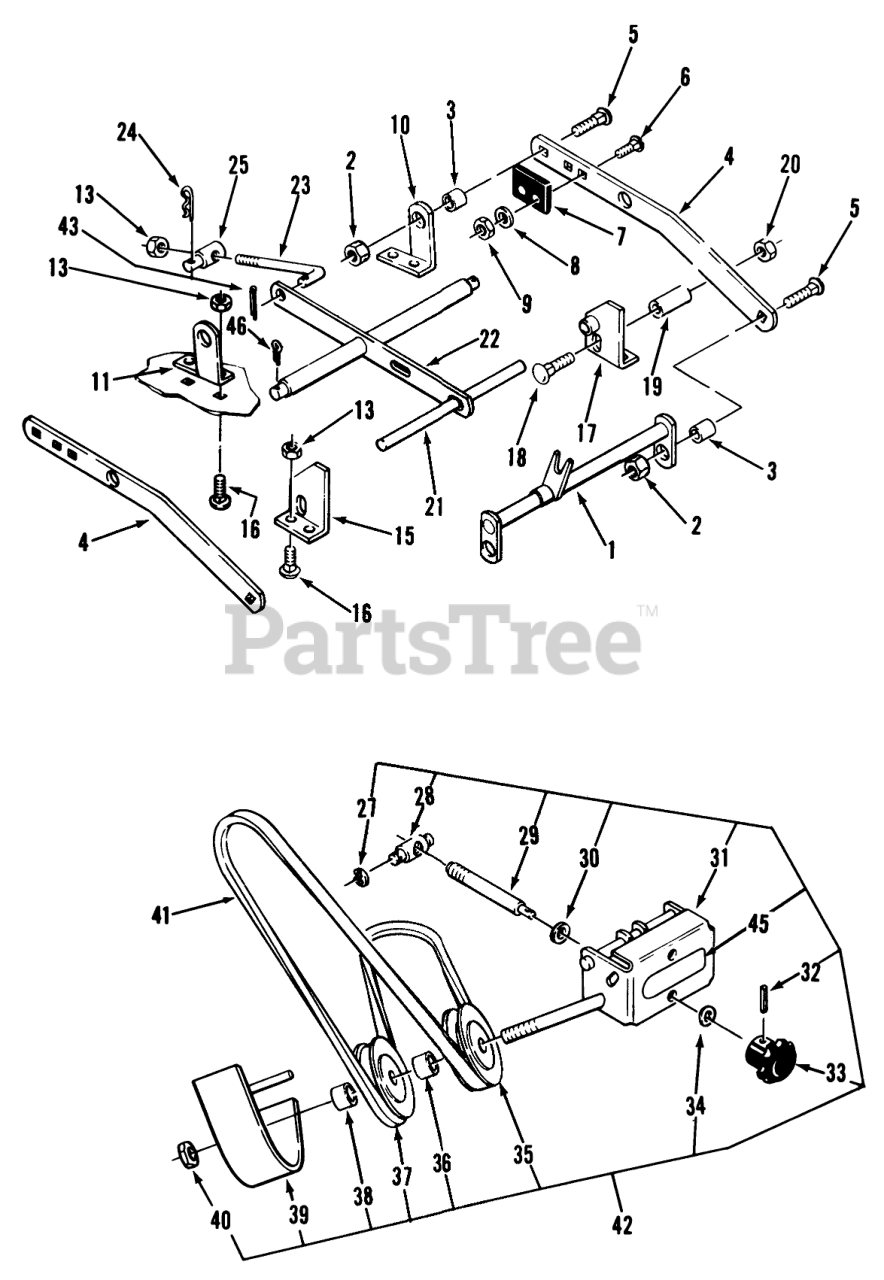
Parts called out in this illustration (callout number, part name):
1	Hitch
2	LOCKNUT-FLANGE
3	SPACER
4	Bar Draft
5	BOLT-CARR
6	SCREW-CARR
7	BUMPER
8	WASHER-FLAT
9	NUT-LOCK, NI
10	LH Rear Bracket
11	Rear Bracket RH
13	NUT-LOCK, NI
15	Front Bracket RH
16	BOLT-CARR
17	Front Bracket LH
18	BOLT-CARR
20	Nut
21	Front Shaft
22	Leveler
23	ROD-LEVEL ADJUST
24	Hairpin
25	TRUNNION-LIFT
27	RING-RETAINING
28	TRUNNION-DOUBLE
29	ROD ADJ
30	WASHER-FLAT
31	Front Support
32	PIN-ROLL
33	KNOB-ADJUSTMENT
34	WASHER-SPRING
35	Pulley-V
36	SPACER
37	PULLEY-FLAT IDLER
38	SPACER-OUTER
39	Belt Cover
40	Nut
41	V-BELT
42	ASM-SUPPORT,IDLER
43	PIN-COTTER
45	Decal-Attac-O-Matic
46	PIN-COTTER
